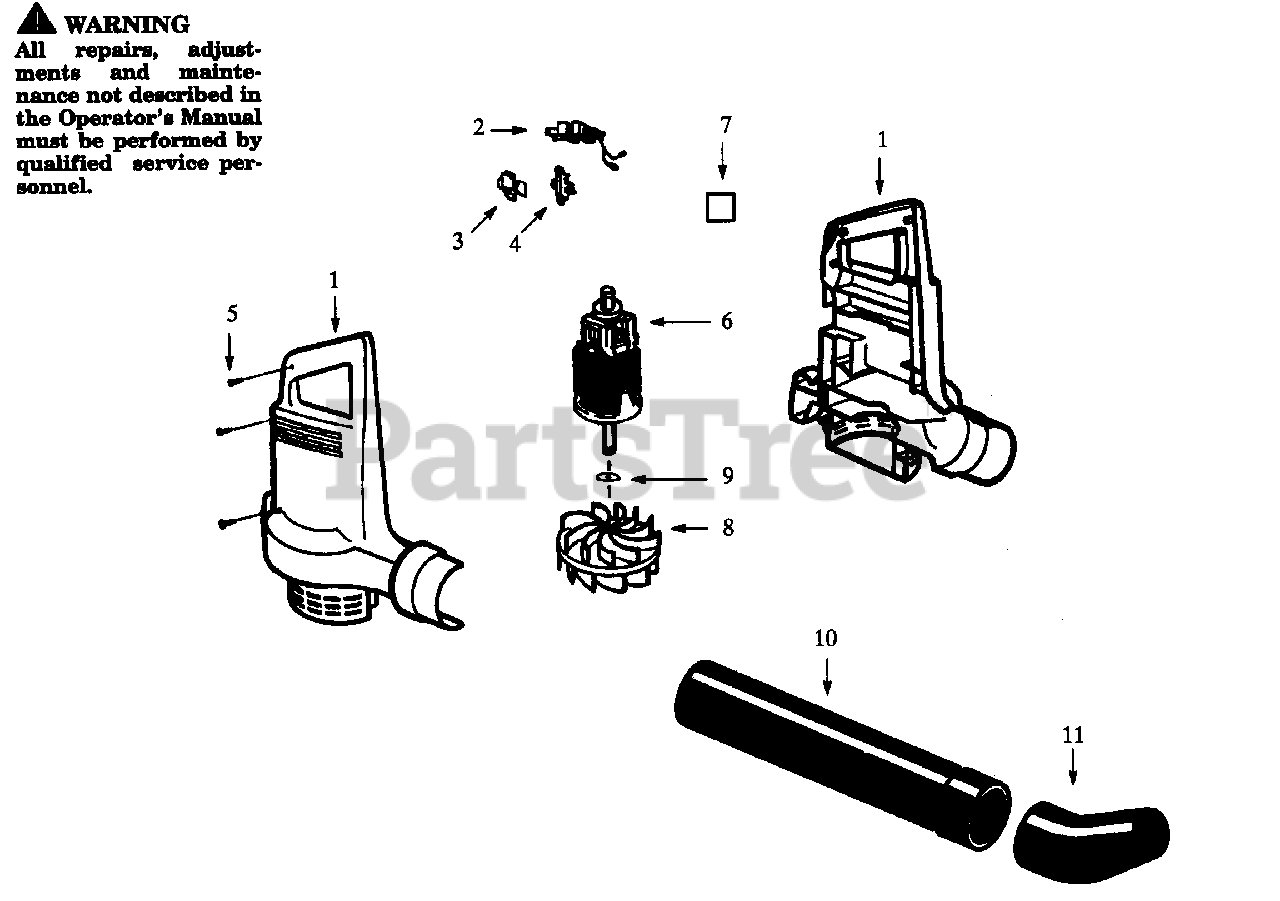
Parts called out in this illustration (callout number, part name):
1	Housing Set
3	Switch Cover
6	Motor Ass'y
8	Impeller
9	Washer-Impeller
10	Blower Tube
11	Concentrator Nozzle
